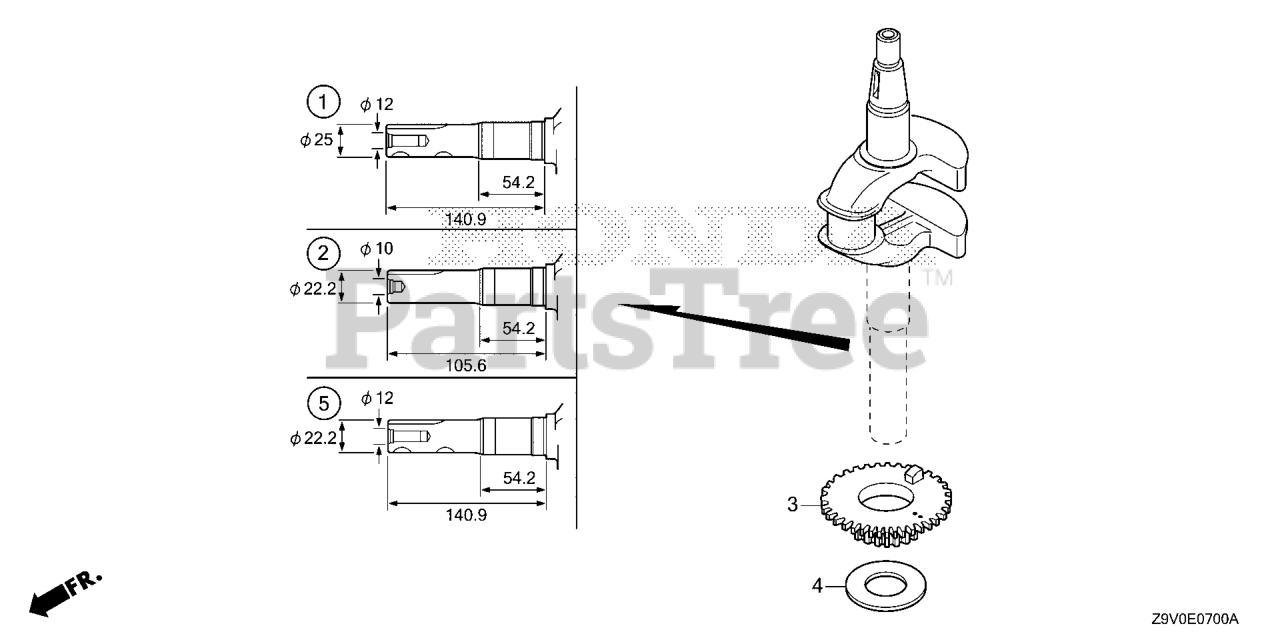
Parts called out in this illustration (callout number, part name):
1	CRANKSHAFT (N3-TYPE)
3	GEAR, TIMING
4	WASHER, THRUST
